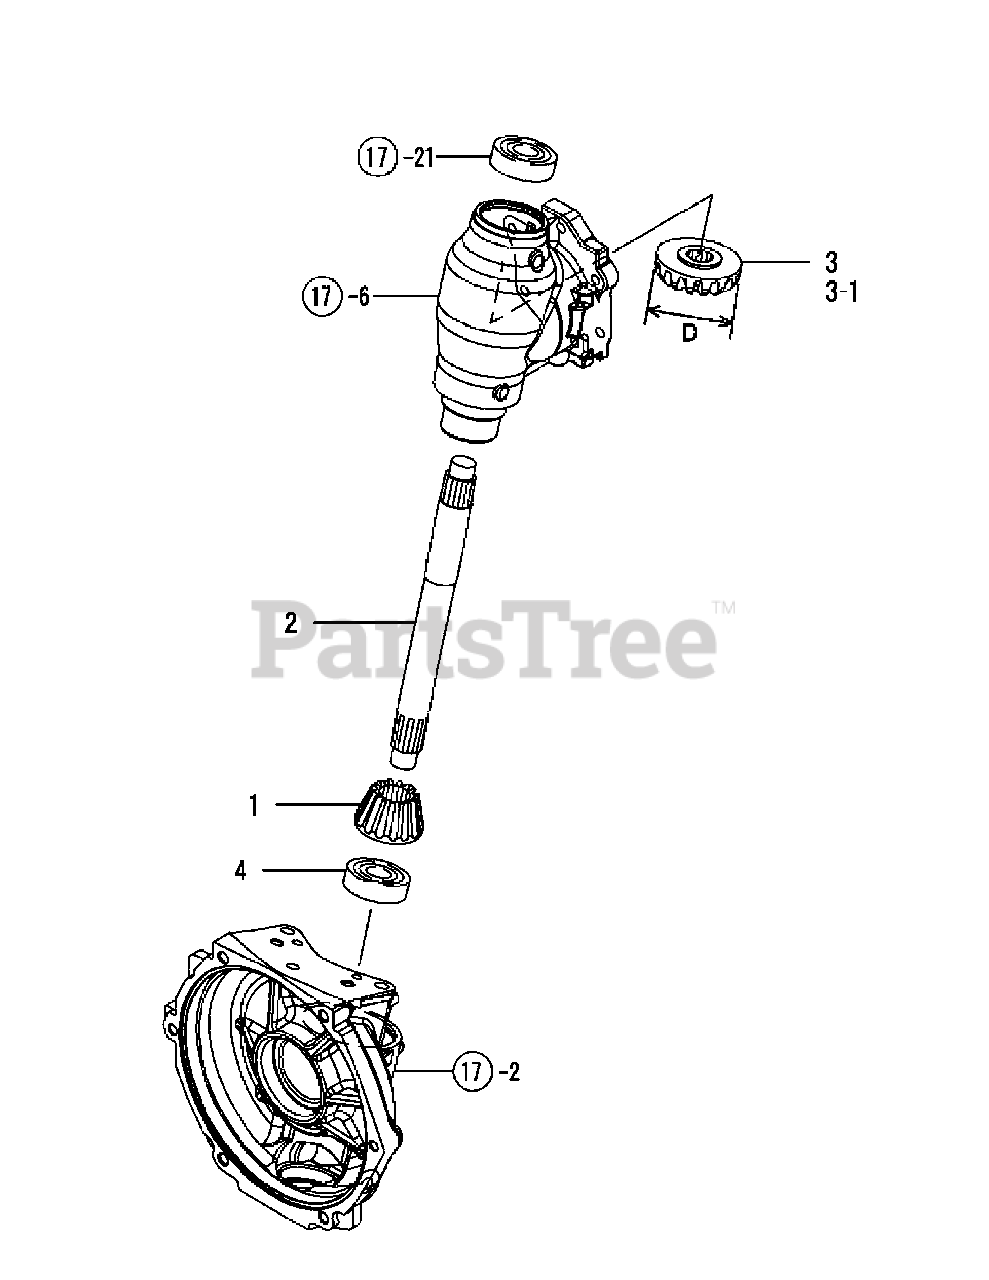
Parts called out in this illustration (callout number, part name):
1	PINION, FRONT FINAL
2	SHAFT, FRONT 2ND
3	GEAR FRONT 2ND Dia.= 69MM
3-1	GEAR FRONT 2ND Dia.= 66MM
4	BEARING 304RSH2
